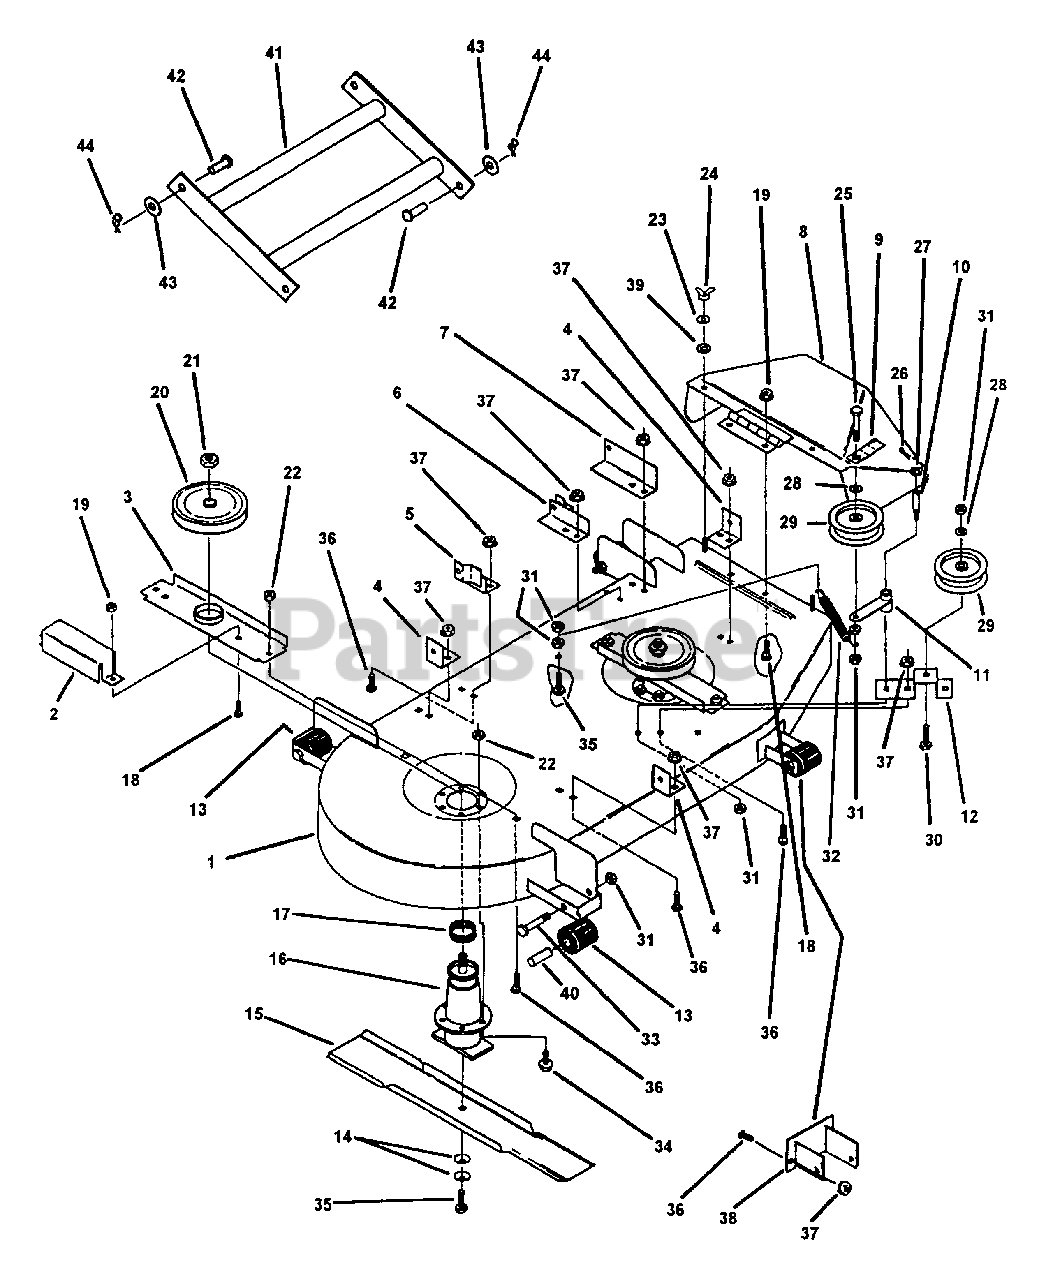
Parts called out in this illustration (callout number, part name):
1	41" DECK SHELL
2	GUARD, PULLEY
3	BRACE, SPINDLE
4	ANGLE, DECK HANGER
5	PIVOT MOUNT WELDMENT L.H.
6	PIVOT MOUNT WELDMENT R.H.
7	ANGLE, DECK HANGER
8	CHUTE ASSEMBLY
9	BELT GUIDE
10	STUD, IDLER
11	IDLER ARM ASSEMBLY
12	BRACKET, IDLER
13	ANTI-SCALP WHEEL
14	WASHER, CONE
15	BLADE, 21"
16	SPINDLE ASSEMBLY
17	TOLERANCE RING, 3/4
18	BOLT, 5/16-18 X 5/8" CARRIAGE
19	NUT, 5/16-18, FLANGED LOCK
20	PULLEY, 5-3/4" O.D.
21	NUT, 3/4-16, JAM
22	NUT, 3/8-16, FLANGE LOCK
23	LOCKWASHER, 5/16" SPLIT SPRING
24	WING NUT, 5/16-18
25	BOLT, 3/8-24 X 2-1 /4"
26	COTTER PIN
27	WASHER, 5/8 SAE
28	SEAL WASHER
29	PULLEY
30	BOLT, 3/8-24 X 1-3/4"
31	NUT, 3/8-24, CENTER LOCK
32	SPRING
33	BOLT, 3/8-16 X 3-3/4"
34	BOLT, 3/8-16 X 3/4", FLANGE LOCK
35	BOLT, 3/8-24 X 1-1/4"
36	BOLT, 3/8-16 X 3/4", CARRIAGE
37	NUT, 3/8-16, FLANGE LOCK
38	BRACKET, ROLLER
39	RETAINER, 5/16" BOLT
40	BUSHING, ROLLER
41	DRAG BAR WELDMENT
42	CLEVIS PIN, 5/16 X 1-1/4" LONG
43	WASHER, FLAT STD. 5/16"
44	COTTER RUE RING, 5/16-3/8 PIN
